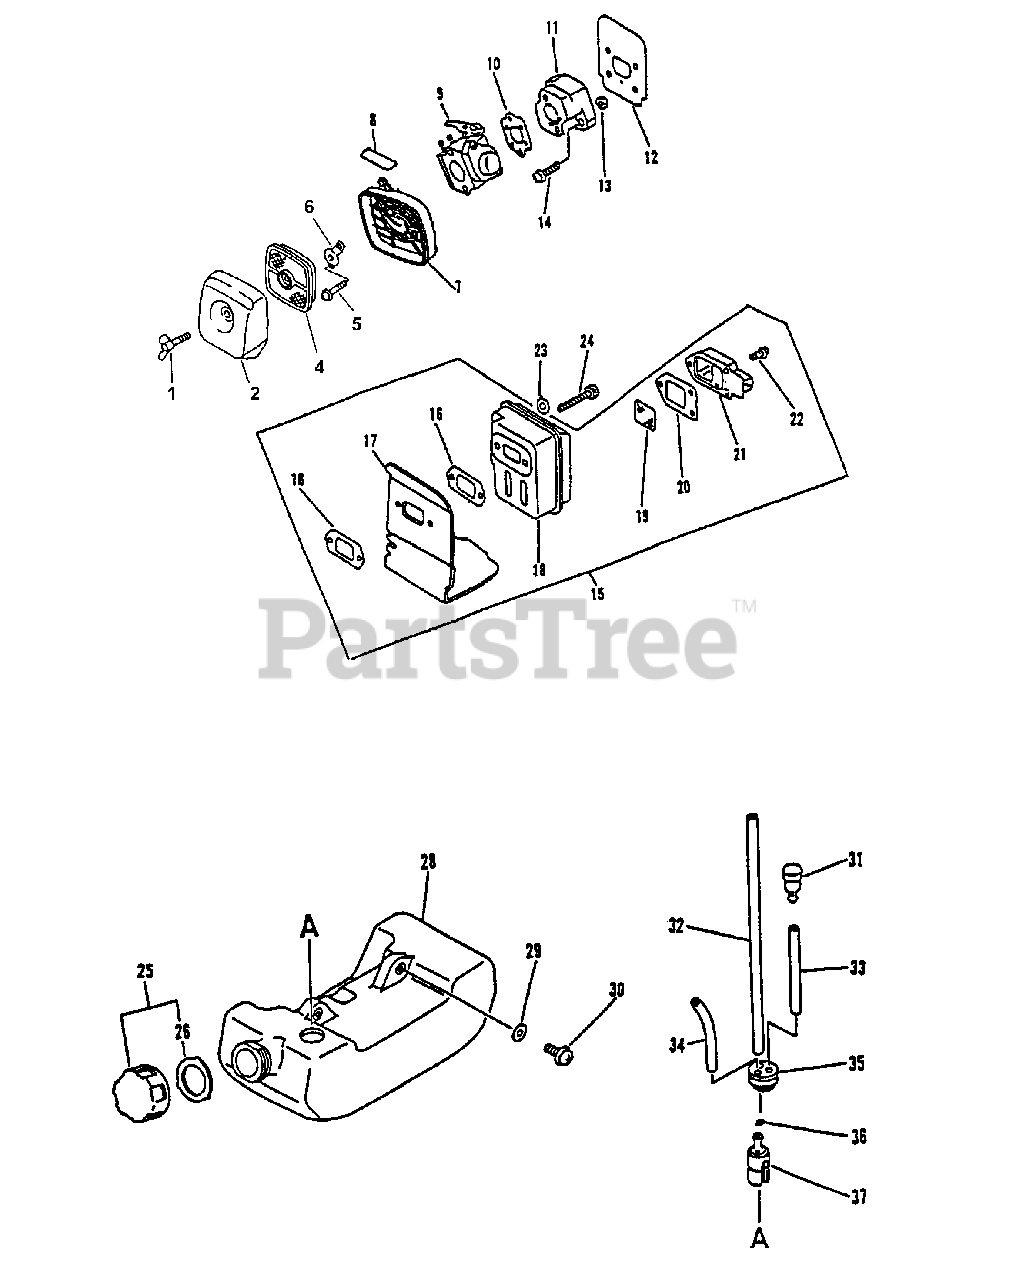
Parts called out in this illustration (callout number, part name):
1	THUMBSCREW
2	COVER, AIR FILTER - GRAY
4	FILTER, AIR - SINGLE LAYER
5	SCREW - 5X65
6	PLATE, PREVENT
7	AIR FILTER CASE ASSY
8	LABEL - CHOKE
9	CARBURETOR C1U-K47
9	CARBURETOR C1U-K52
10	GASKET, INTAKE
11	INSULATOR, INTAKE
12	SHIELD, INTAKE
14	SCREW - 5X20
15	MUFFLER ASSY
16	GASKET, EXHAUST
17	COVER, EXHAUST
19	SCREEN, SPARK ARRESTOR
20	GASKET, EXHAUST
21	GUIDE, EXHAUST - OUTER
22	SCREW - 4X10
23	WASHER - 5
24	SCREW - 5X55
25	CAP ASSY
26	GASKET, CAP
28	TANK, FUEL
29	WASHER - 5
30	SCREW - 5X16
31	VENT, FUEL TANK
32	PIPE - 3X5X180 -- BLACK
33	PIPE - 3X5X70 -- BLACK
34	PIPE - 3X6X80 -- CLEAR
35	GROMMET
36	CLIP - 6
37	FILTER, FUEL
